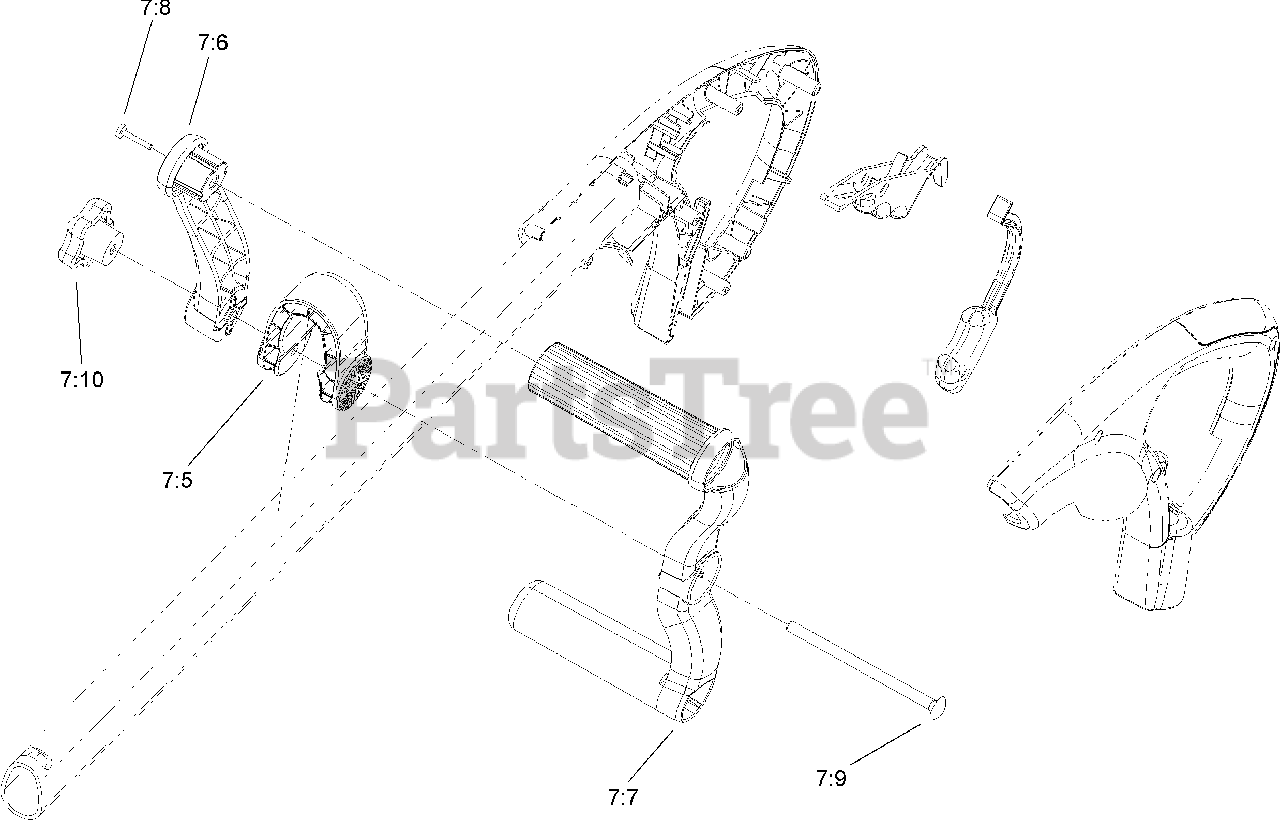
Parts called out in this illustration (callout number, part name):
7:5	COLLAR-HANDLE, ASSIST
7:6	HANDLE-ASSIST, RIGHT
7:7	HANDLE-ASSIST, LEFT
7:8	SCREW-PPH
7:9	SCREW-CARRIAGE
7:10	KNOB-HANDLE
